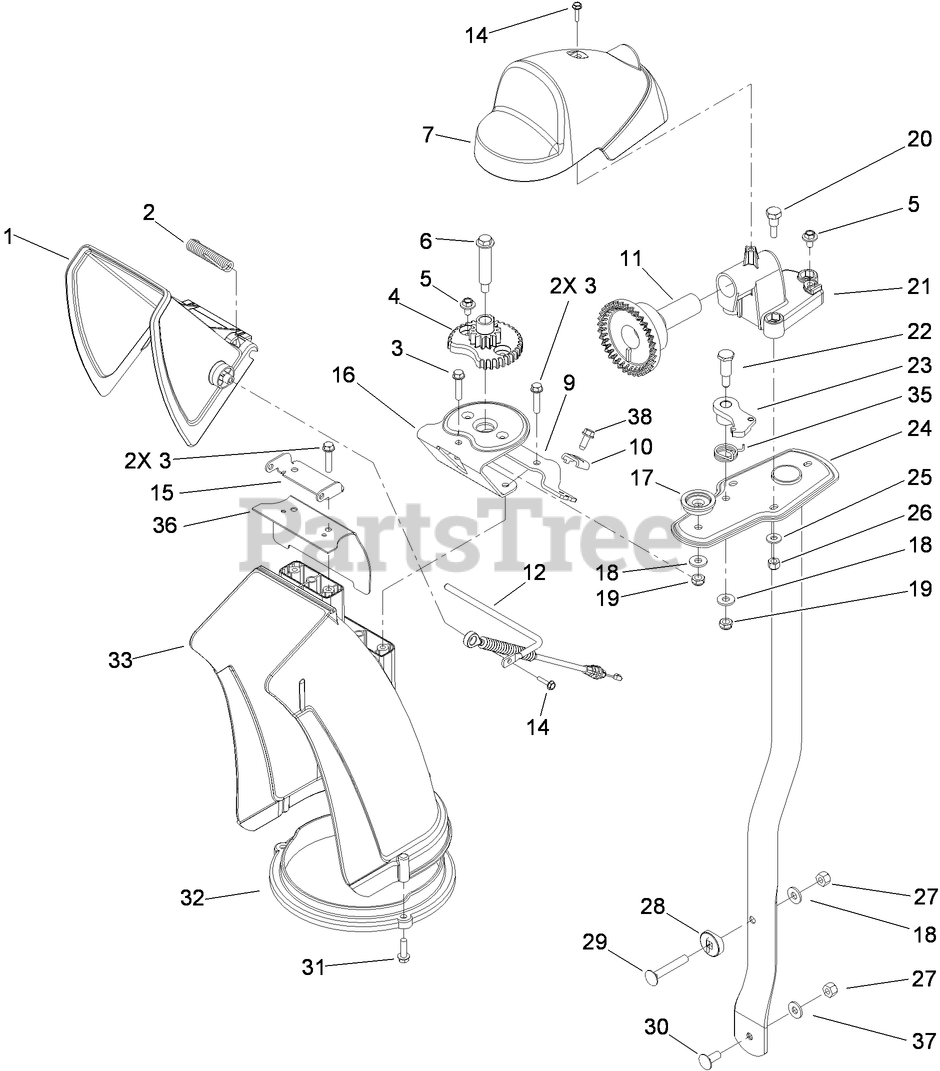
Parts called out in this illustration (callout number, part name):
1	DEFLECTOR-CHUTE, CE
2	SPRING-TORSION
3	SCREW-PLASTITE
4	GEAR-CHUTE
5	SCREW AND WASHER ASM
6	BOLT-SHOULDER
7	COVER-GEAR, CHUTE
9	BRACKET-CABLE, CLAMP
10	CLAMP-CABLE
11	GEAR-FACE
12	ROD-DEFLECTOR
14	SCREW-HWH
15	BRACKET-DEFLECTOR
16	BRACKET-SUPPORT, CHUTE
17	SPACER-CHUTE
18	WASHER-FLAT
19	NUT-LOCK, NI
20	SCREW-SHOULDER
21	MOUNT-GEAR, FACE
22	SCREW-SHOULDER
23	LATCH-CHUTE
24	TUBE-SUPPORT
25	WASHER-FLAT
26	NUT-LOCK, NI
27	NUT-LOCK, NI
28	WASHER-CURVED
29	BOLT-CAR
30	SCREW-CARR
31	SCREW-HWH
32	RING-CHUTE
33	CHUTE-DISCHARGE
35	SPRING-TORSION
36	SEAL-CHUTE
37	WASHER-BELLEVILLE
38	SCREW-HWH
